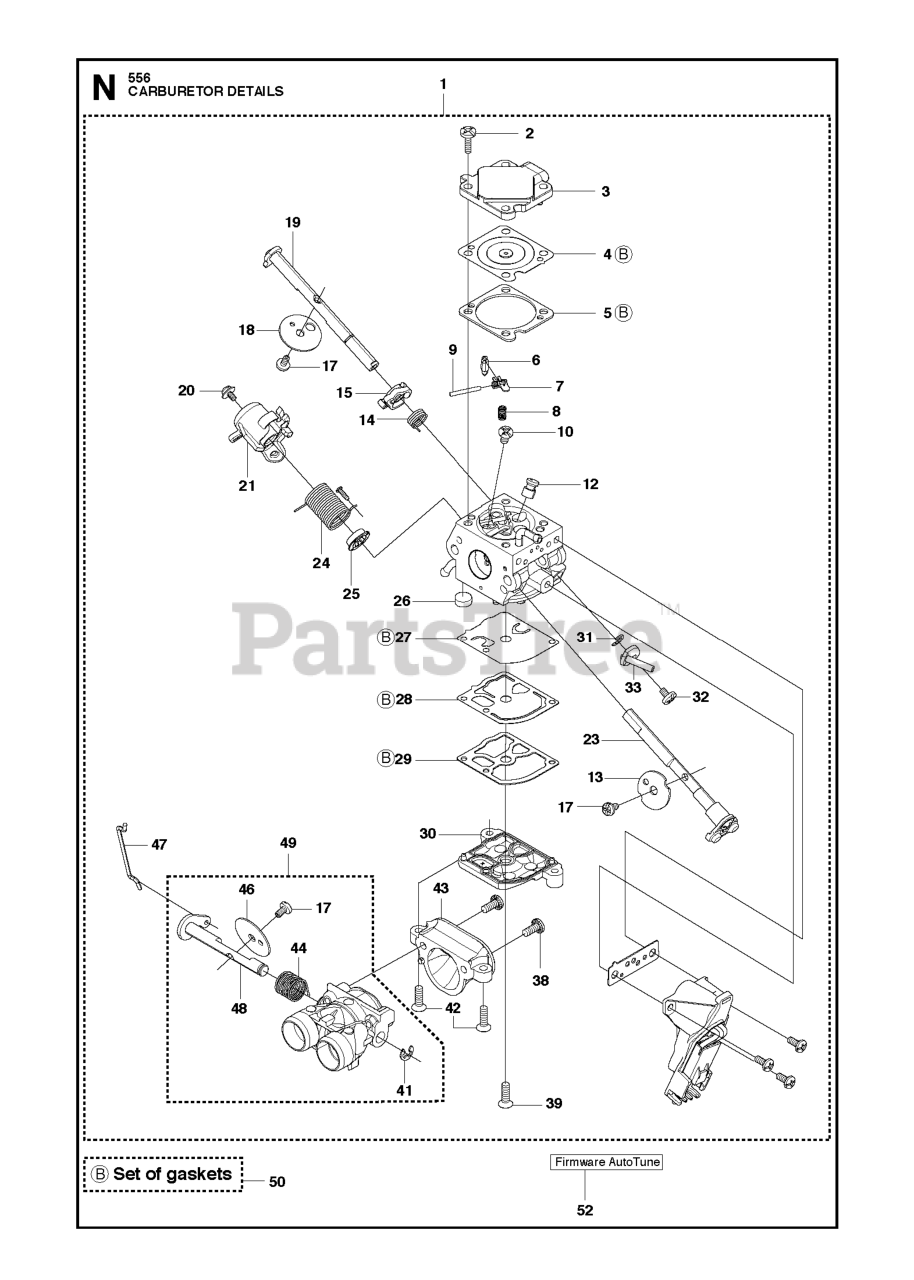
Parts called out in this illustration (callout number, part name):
1	BATTERY BATTERY 14AH 12V LEOC
2	SCREW.HEX.HEAD.CAP.M6 X1.12W
16	SWITCH INTERLOOK PUSH-IN
21	HARNESS.LIGHT W/4152J BULBS
25	CABLE CABLE.RED.20.8AWG.M6.CRD
26	FUSE 20AMP
27	NUT
28	CABLE CABLE.BLACK.20.8AWG.M6.C
29	SWITCH.SEAT.DELTA.OPC.
30	SWITCH.IGN.DELTA.W.LGH.ROS
33	KEY.CHAIN.BLISTER.PACK.GEN.INT
40	HARNESS.DASH.ELECT.SRD.BAT.CHR
43	SOLENOID.W/BRASS.PLUNGER
46	RP.GUAGE.SRVCMNDR.HRMTR.
50	RP.PTO.SWITCH.8 TERMINAL.BLACK
55	SCREW 5/16"
71	HARNESS.CH.TCRD.HYD.TWIN.ELD.
75	SWITCH.BAG.DUMP
79	BULB HOLDER ASM.
83	NUT NUT SQUARE
99	SCREW
102	HARNESS ASSY
105	REVERSE SWITCH
107	.WITCH.FULL BAGGER.INDICATOR
108	SWITCH.SNAPMOUNT.NC
142	RP HARNESS.JUMPER.CTEK
